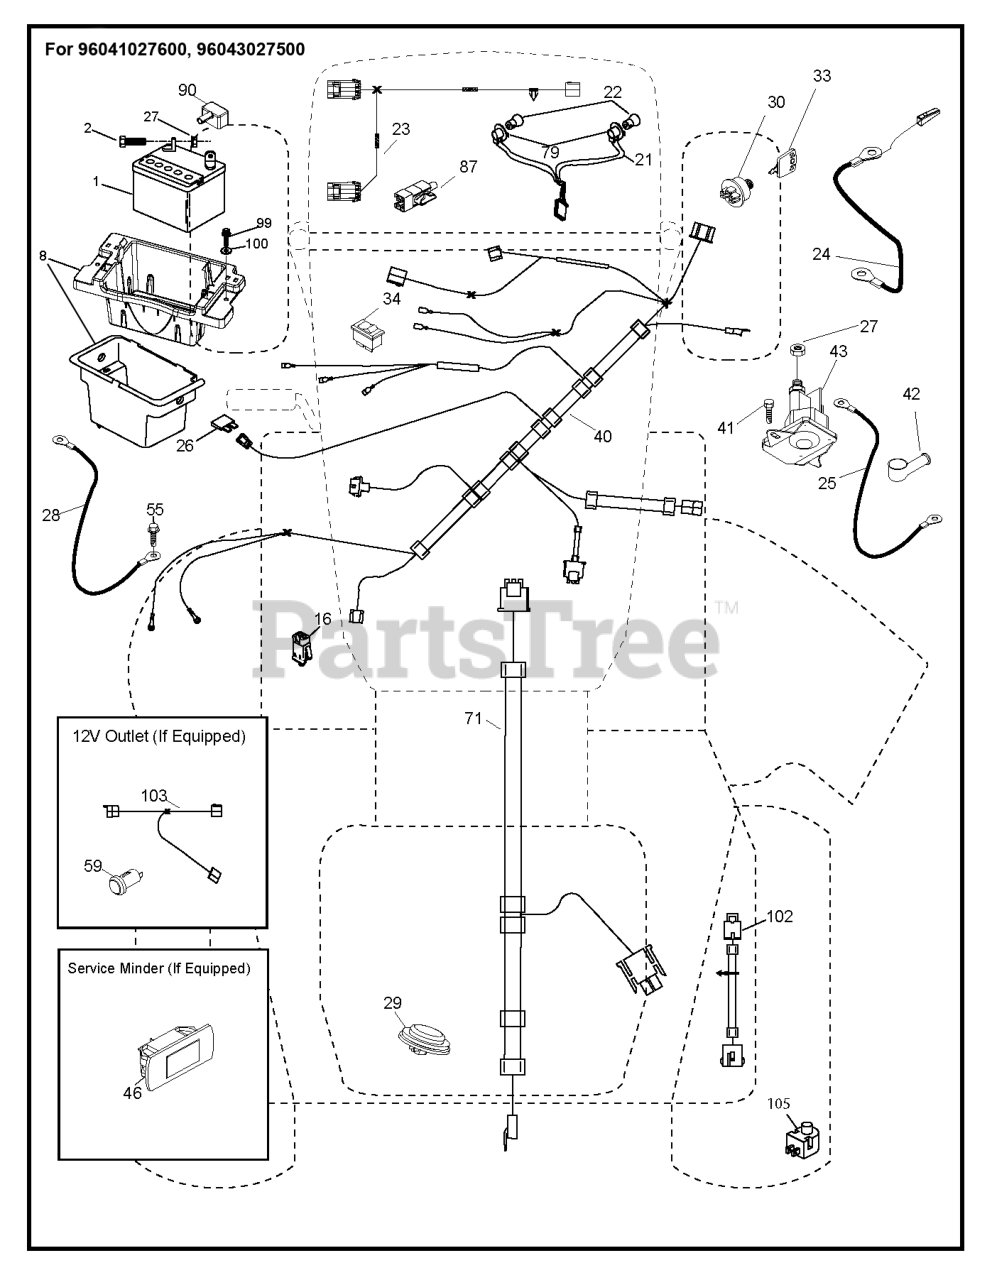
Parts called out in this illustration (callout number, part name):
1	Battery 12 Volt 25 Amp
2	BOLT.HEX.1/4.X.3/4.DICHROMATE
8	BOX.BATTERY.MNT.REAR.L
8	TRAY.ASM.BATTERY.FRT.TEX.CARB
16	SWITCH INTERLOOK PUSH-IN
21	HARNESS.LIGHT W/4152J BULBS
22	LIGHTBULB
23	HARNESS LIGHT ASSY TRACTOR,
24	CABLE.FRBATT.W/WIRE.8GA.8
25	CABLE.STARTER.8GA.17.5
26	FUSE 20AMP
27	NUT
28	CABLE.GROUND.21"BLK.8GA.90T
28	CABLE.BLACK.18"REAR.BA
29	SWITCH.SEAT.DELTA.OPC.
30	SWITCH.IGN.DELTA.W.LGH.ROS
33	KEY.CHAIN.BLISTER.PACK.GEN.USA
40	HARNESS.IGN.DASH.CBL.YTGT.PRED
40	HARNESS IGN. DASH
41	SCREW
42	TERMINAL COVER
43	SOLENOID.STARTER.BRASS.PLUNGER
46	RP.GUAGE.SRVCMNDR.HRMTR.
46	GUAGE.SRVCMNDR.HRMTR.
55	SCREW 5/16"
71	HARNESS.IGN.CHASS.TEX.REAR.BAT
71	HARNESS-CHASSIS SUB
79	BULB HOLDER ASM.
87	SWITCH.INTRLCK.CLUTCH.
90	COVER.TERMINAL.BATTERY
99	SCREW HEXWSHR 1/4-20X3/4
100	WASHER
102	HARNESS PIGTAIL PCH TEX ROS
105	REVERSE SWITCH
